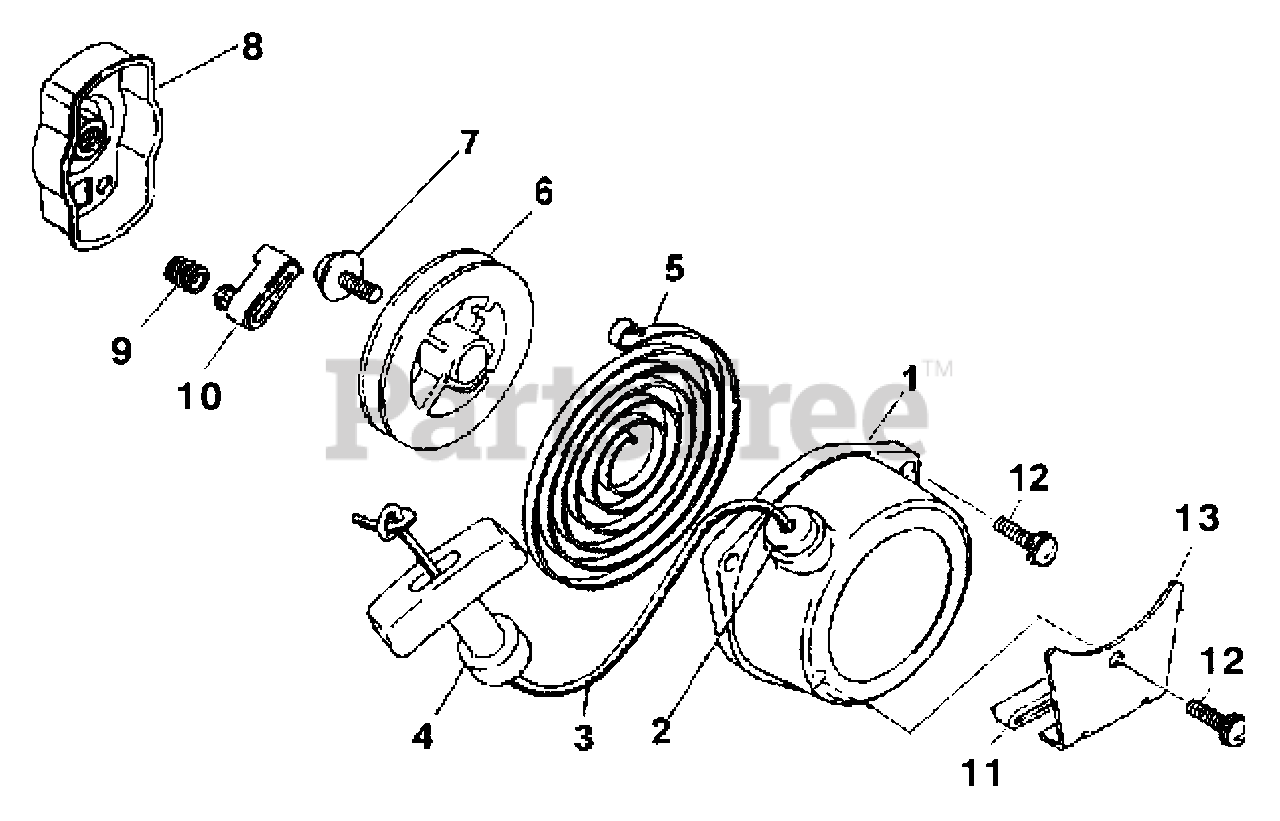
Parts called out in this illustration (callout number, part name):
1	STARTER ASSY
3	ROPE, STARTER
4	KNOB, STARTER
5	SPRING, REWIND
7	SCREW & WASHER
8	PULLEY ASSY, STARTER
9	SPRING, RETURN
10	RATCHET
12	SCREW & WASHER
13	BRACKET
